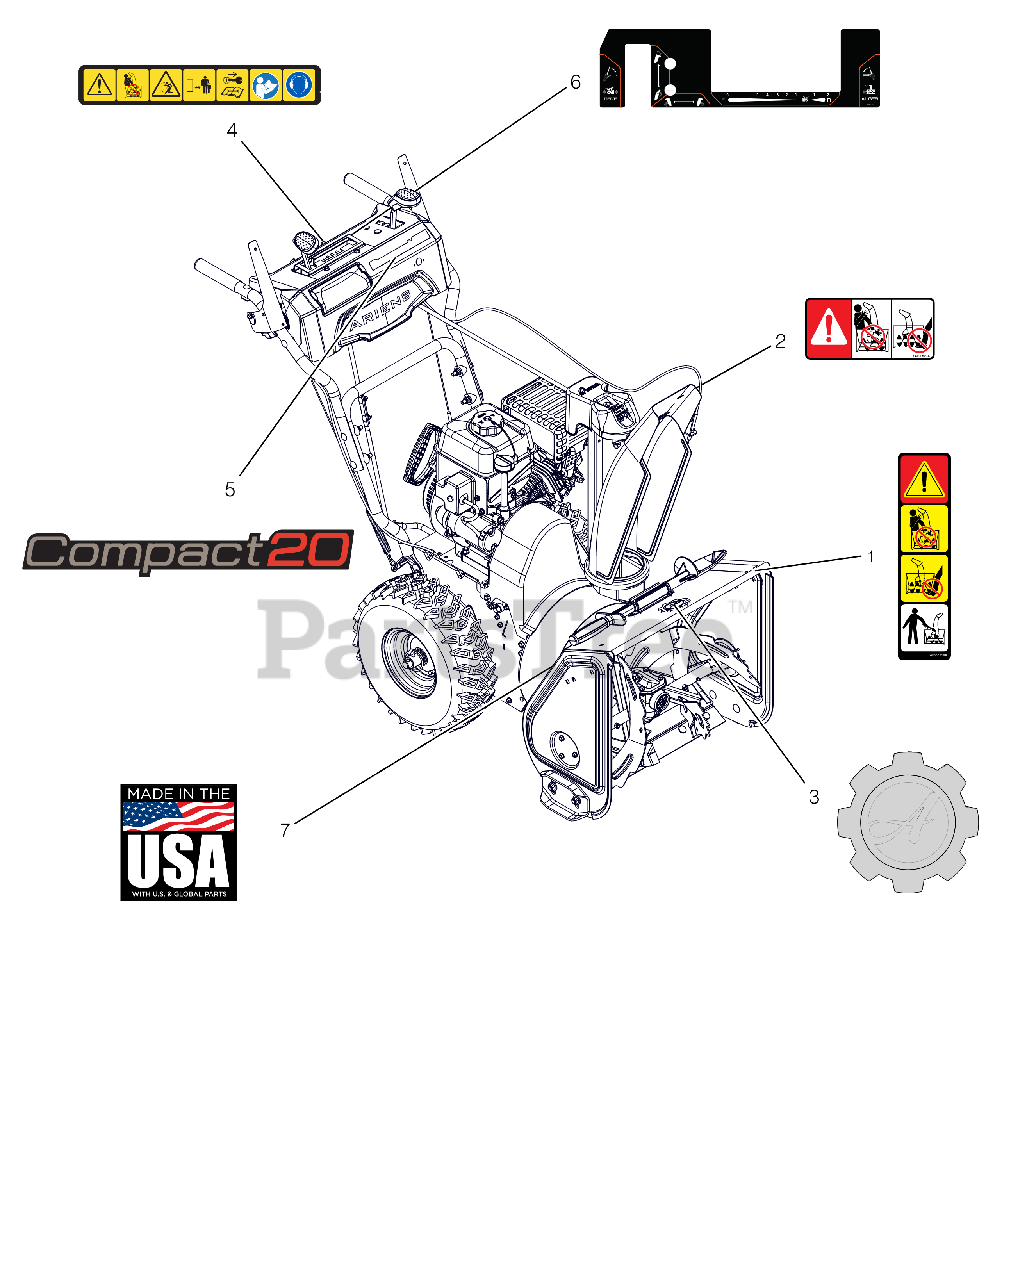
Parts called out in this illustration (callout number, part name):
1	DECAL, DANGER - ROTATING PARTS
2	DECAL, DANGER
3	DECAL, ARIENS-GEAR BADGE -THK
4	DECAL,DASH - SAFETY
5	DECAL, DASH - COMPACT 20
6	DECAL,CONTROL-COMP REMOTE
7	DECAL, MADE IN USA
